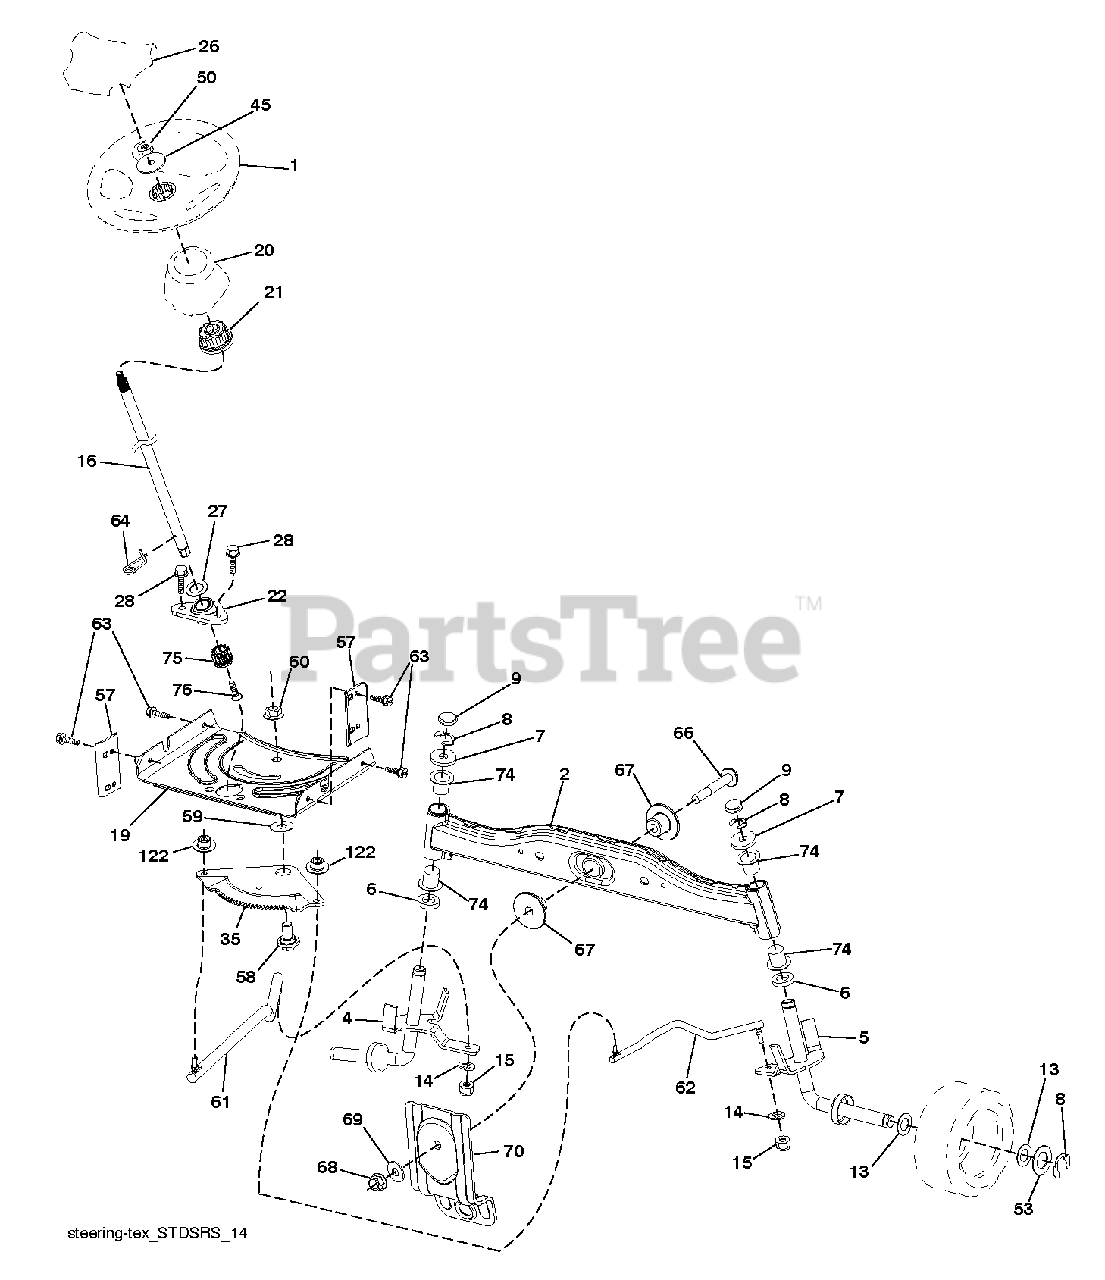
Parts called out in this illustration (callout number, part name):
1	WHEEL.STEERING.HARD.RIM.BLAC
2	AXLE HALF ASM-WELDED
4	SPINDLE.WELDED.LH.15"TEX
5	SPINDLE.WELDED.RH.15"T
8	RING CLIP
9	CAP.SPINDLE.BLACK
14	WASHER, LOCK 3/8
15	NUT CROWNLOCK 3/8-24
19	PLATE.STEER.DDL.NLT/NG
20	BOOT.STRNG.PREDATOR.YT/GT.428
26	INSERT, WHEEL STEERING
27	WASHER LT
28	SCREW, 3/8-16X3/4
35	GEAR.SECTOR.PLATE.DDL.
45	WASHER.3/8ID.2-3/8OD.12GA.PLTD
50	NUT LOCK FLG 3/8-16 UNC
53	WASHER.HARDENED
57	BRACKET.UPSTOP.TEX
58	BOLT.SHOULDER.SECTOR.P
59	WASHER.THURST.SECTOR.S
60	NUT FLANGE LOCK 5/8-11
61	DRAGLINK.LH.BALLSTUD.D
62	DRAGLINK.RH.BALLSTUD.D
63	SCREW
64	RETAINER.CLIP.SPRING.S
66	BOLT HEX FGHD 7/16-14 X 3 SERR
67	BUSHING.PM.FRONT AXLE
68	NUT.LOCK.FLANGE.7/16
69	WASHER.1.5X.505X.118
70	Deck Suspension Bracket, Front RR
74	Steering Column Bearing
76	Screw Head Socket Lrvb
122	CAP.GEAR.SECTOR.TEX
